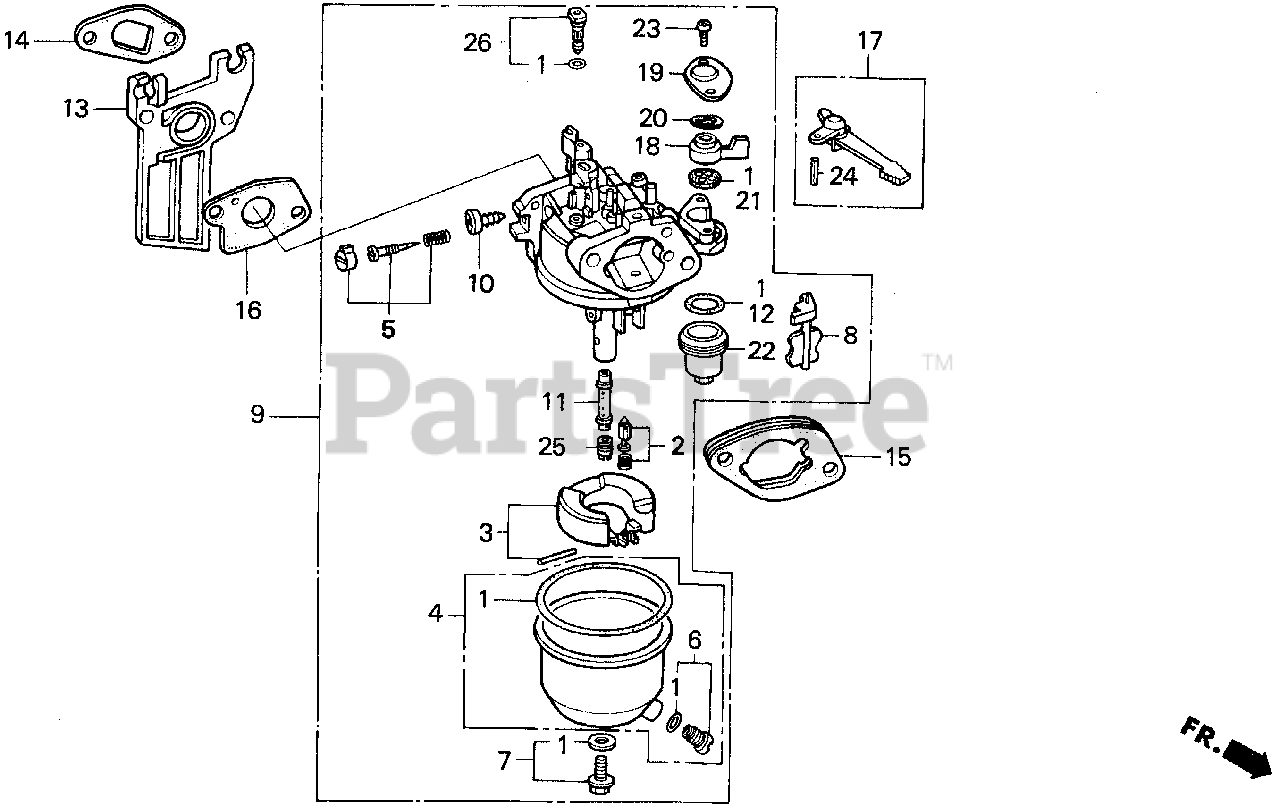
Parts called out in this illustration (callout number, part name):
1	GASKET SET
2	VALVE SET, FLOAT (SEAT NOT INCLUDED)
4	CHAMBER SET, FLOAT
5	SCREW SET, PILOT
6	SCREW SET, DRAIN
7	SCREW SET
9	CARBURETOR ASSY. (BE60B B)
10	SCREW, THROTTLE STOP
11	NOZZLE, MAIN
12	GASKET, FUEL STRAINER CUP
13	INSULATOR, CARBURETOR
14	GASKET, INSULATOR
15	SPACER, CARBURETOR
16	GASKET, CARBURETOR
17	LEVER, CHOKE (STD)
18	LEVER, VALVE
18	LEVER, PETCOCK
19	PLATE, LEVER SETTING
20	SPRING, PETCOCK LEVER
21	GASKET, PETCOCK
22	CUP, FUEL STRAINER
23	SCREW, PAN (3X8)
24	PIN, SPRING (2X12)
25	JET, MAIN (#55)
25	JET, MAIN (#60)
25	JET, MAIN (#58)
26	JET SET, PILOT (#35)
